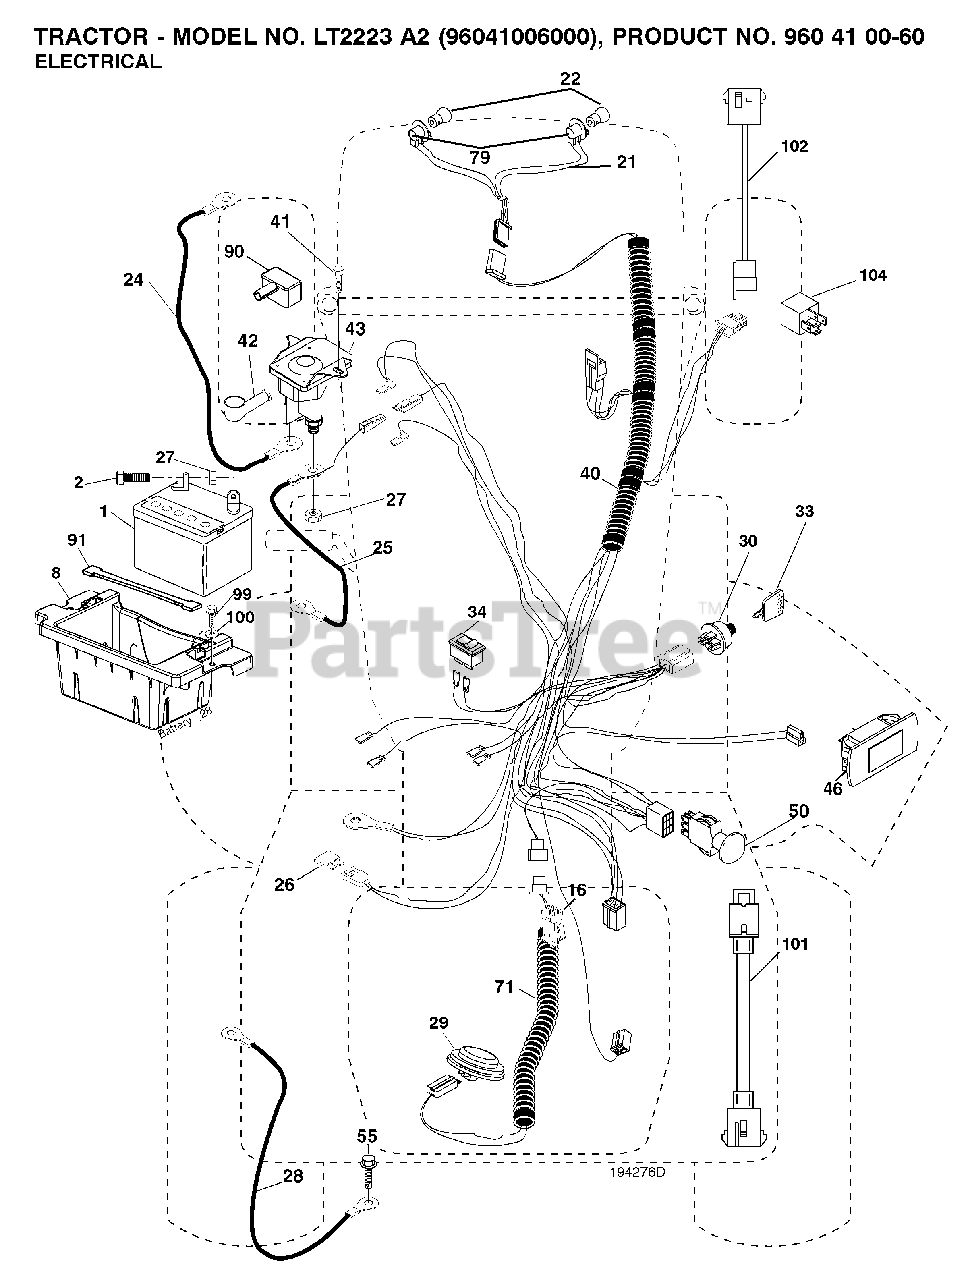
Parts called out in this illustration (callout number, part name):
1	BATTERY 12V .35 AMP
8	BOX.BATTERY.MOUNT.FRONT.LT
16	SWITCH INTERLOOK PUSH-IN
21	HARNESS.W/LIGHT SOCKET
22	LIGHTBULB
24	CABLE.BATT.POS.WIRE.TG.DA SOL
25	CABLE.START.RED.17.5".
26	FUSE 20AMP
27	NUT
28	CABLE GROUND 6 GA 21" 90T BLK
29	SWITCH.SEAT.DELTA.OPC.
30	SWITCH.IGN.DELTA.W.LGH.ROS
33	KEY MLD GEN DELTA
34	SWITCH LT
40	HARNESS.IGN.ELE.RELAY.TEX.46"
41	SCREW
42	TERMINAL COVER
43	SOLENOID.W/BRASS.PLUNG
46	GUAGE.SRVCMNDR.HRMTR.
50	PTO SWITCH
55	SCREW 5/16"
71	HARNESS-CHASSIS SUB
79	BULB HOLDER ASM.
90	COVER.TERMINAL.BATTERY
91	STRAP, BATTERY MOUNT
99	SCREW HEXWSHR 1/4-20X3/4
101	PIGTAIL.MATNLK.NEW.HAR
102	HARNESS PIGTAIL PCH TEX ROS
104	RELAY HARNESS.SEALED
